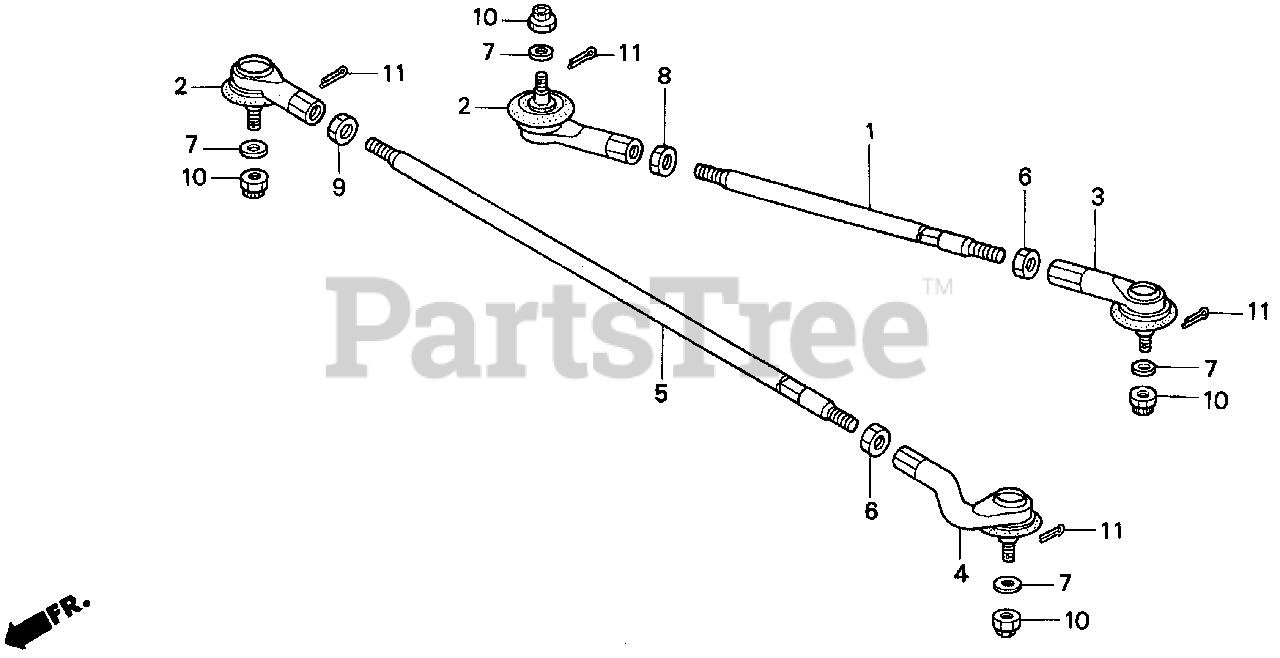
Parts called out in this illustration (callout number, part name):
2	END, R. TIE ROD
3	END, L. TIE ROD
4	END, L. TIE ROD
5	TIE ROD B
6	NUT, HEX. (14MM) (L)
7	WASHER, SPECIAL (24X12X2.3)
8	NUT, HEX. (14MM)
9	NUT, HEX. (14MM)
10	NUT, CASTLE (12MM)
11	PIN, COTTER (3.0X45)
